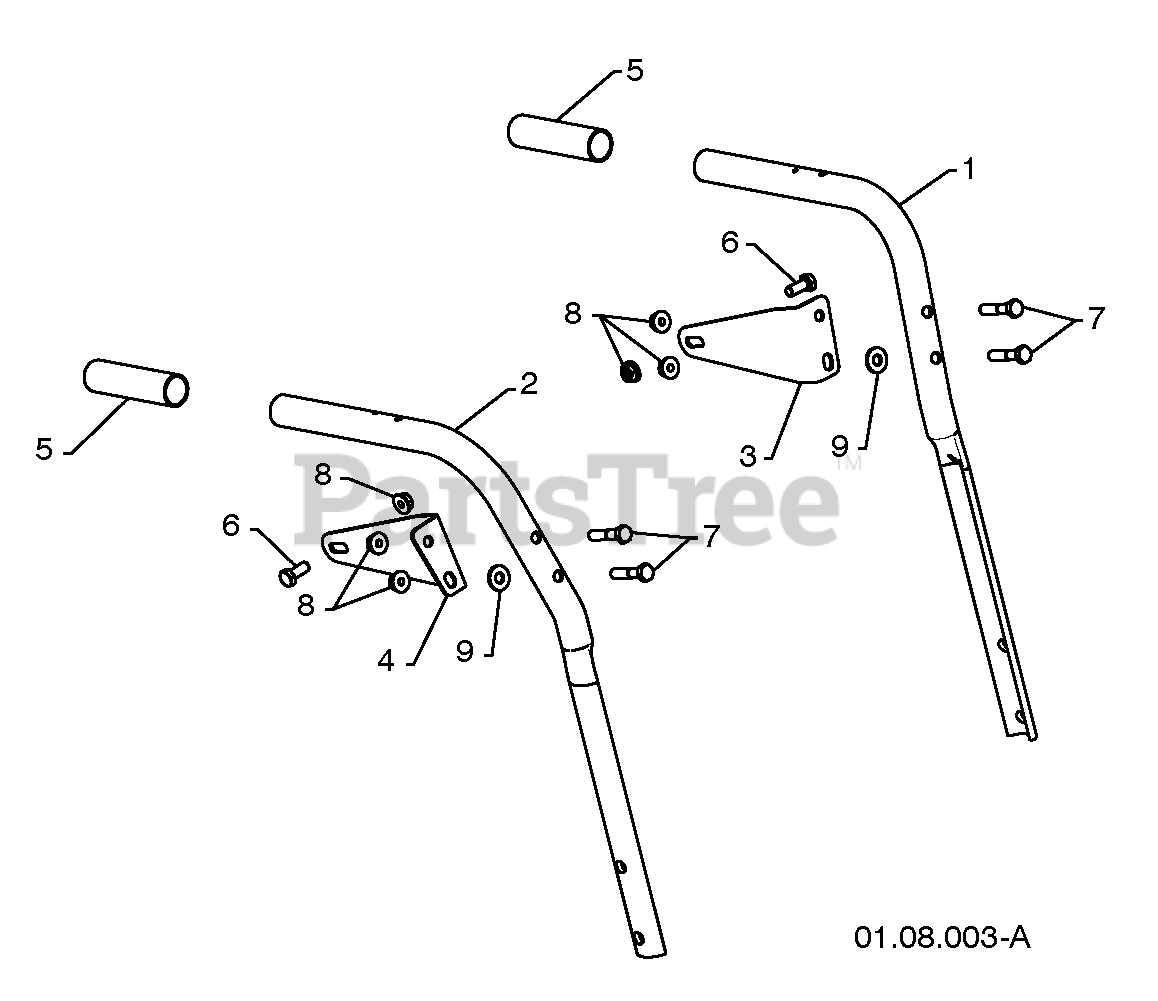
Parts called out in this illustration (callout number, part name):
1	PLOW HANDLE LH
2	PLOW HANDLE RH
3	PANEL BRACKET LH
4	PANEL BRACKET RH
5	HANDLE GRIP
6	SCREW 5/16-18 X .750
7	SCREW 5/16-18 X 1.50
8	NUT 5/16-18
9	WASHER
